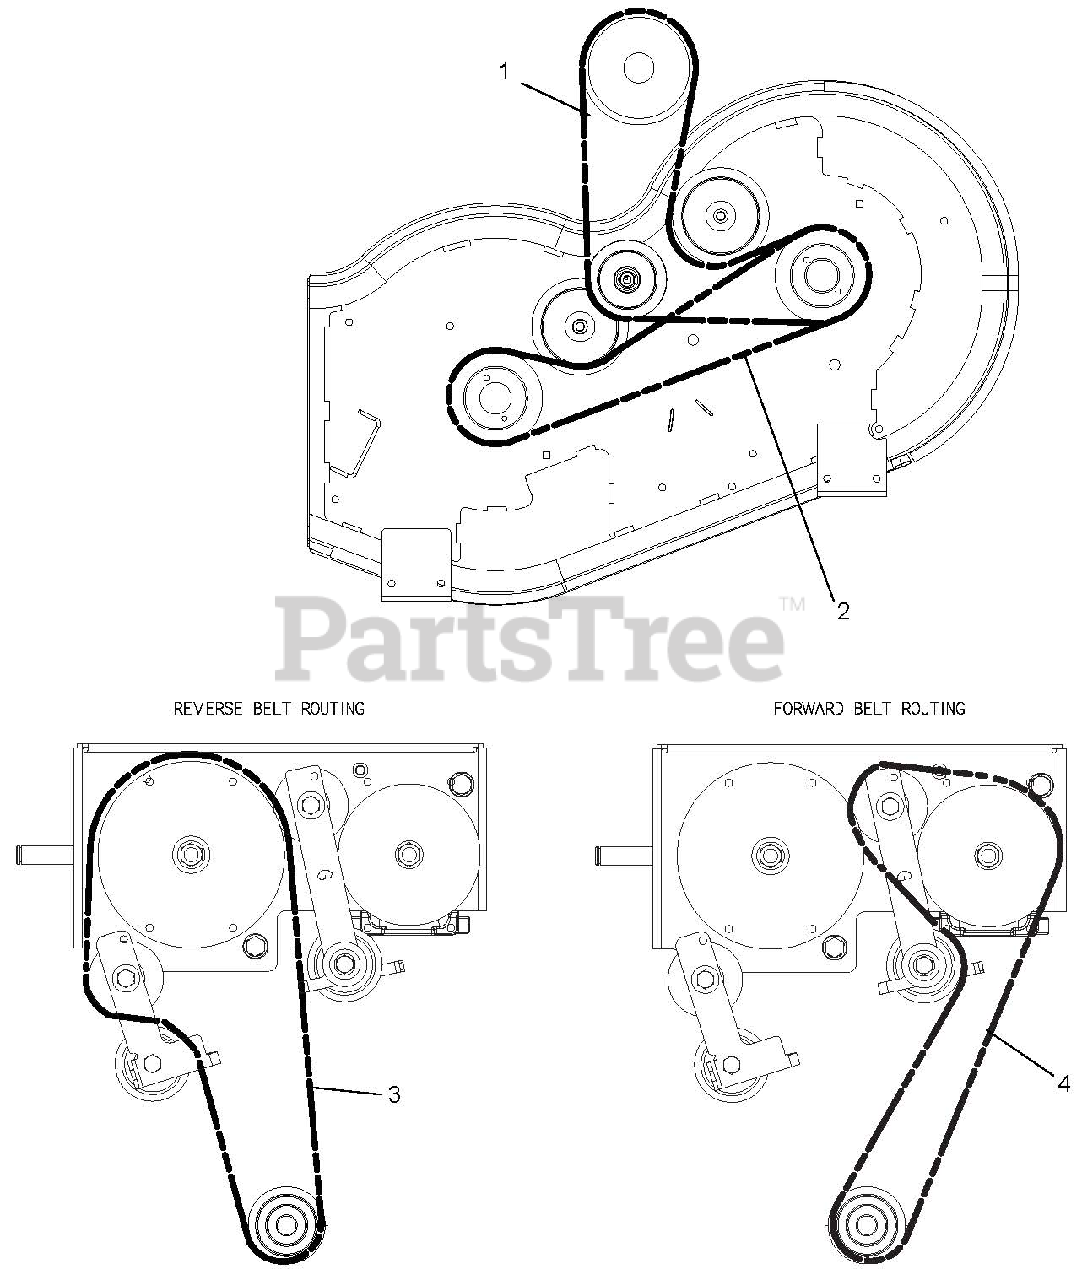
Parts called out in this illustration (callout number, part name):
1	V-BELT, HA-WRAPPED
2	V-BELT, HA-WRAPPED
3	V-BELT, 3L-WRAPPED
4	V-BELT, 3L-WRAPPED
